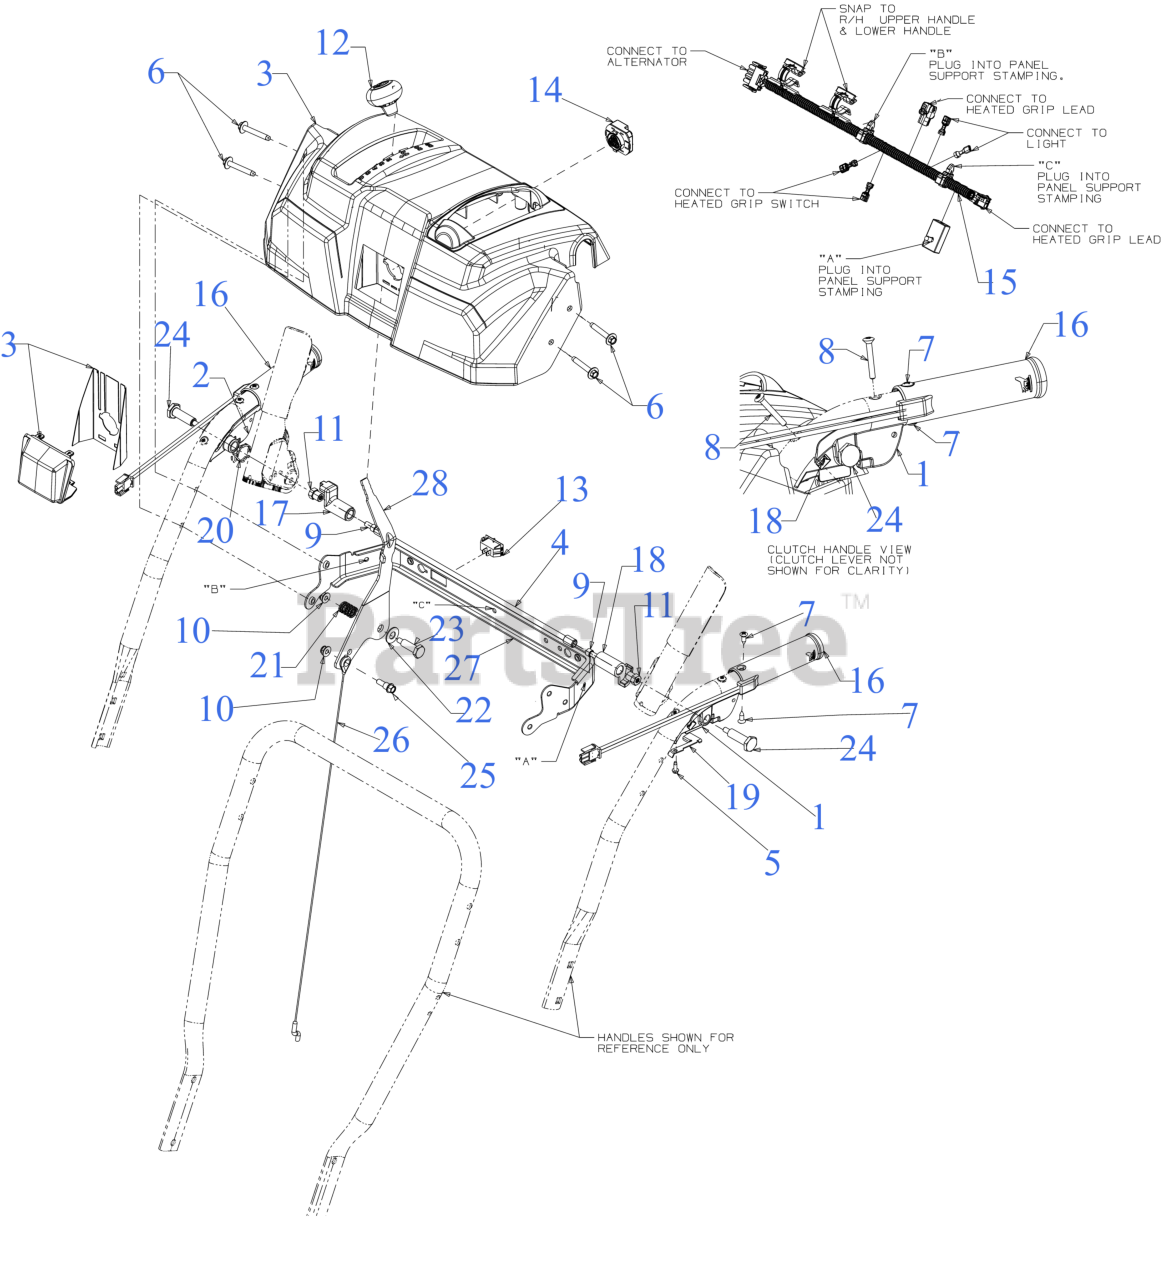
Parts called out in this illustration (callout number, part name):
1	CLUTCH LOCK HANDLE ASSEMBLY (LH)
2	CLUTCH LOCK HANDLE ASSEMBLY (RH)
3	HANDLE PANEL ASSEMBLY
5	SCREW #8-16 x .50
6	SCREW 1/4-20 x 1.625
7	SCREW-AB #12-24 x .625
8	SCREW #10-24 x 1.375
9	SCREW 1/4-20 x .50
10	FLANGE LOCK NUT
11	HEX NUT W/PATCH
12	SHIFT KNOB
13	HEATED GRIP SWITCH
14	LED HEADLIGHT & SOCKET (150 LUMNES)
15	HEATED GRIPS HARNESS
16	HEATED GRIP
18	CLUTCH LOCK CAM
19	CLUTCH SPRING
20	TORSION SPRING
21	COMPRESSION SPRING
22	FLAT WASHER .38X.88
23	SHOULDER SCREW
24	SHOULDER SCREW .437 x 1.345 1/4-20
25	SHOULDER SCREW .342X.335X1/4-20
26	SELECTION CABLE
